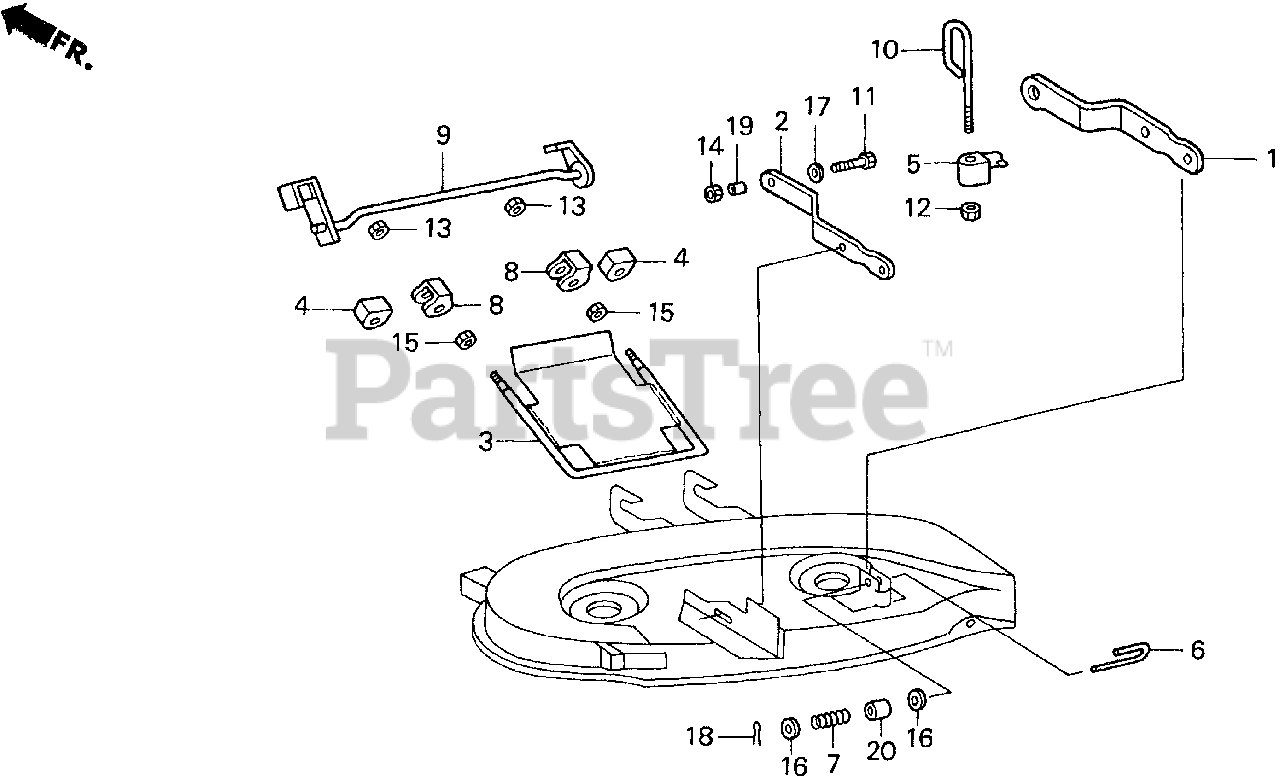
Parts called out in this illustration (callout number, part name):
1	LINK, R. RR. DECK
2	LINK, L. RR. DECK
3	ROD, CUTTER DECK LIFT
4	PIN, RR. LINK ADJUSTING
5	PIN, RR. LINK ADJUSTING
6	PIN, LIFT ARM
7	SPRING, LIFT ARM PIN
8	BRACKET, FR. LINK
10	BAR, ADJUSTING
11	BOLT, HEX. (12X35)
12	NUT, NYLON LOCK
13	NUT C, LOCK (8MM)
14	NUT, LOCK (12MM)
15	NUT, HEX. (12MM)
16	WASHER, RELEASE PIN
17	WASHER, RR. DECK LIFT
18	PIN, DRAFT ARM COTTER
19	BUSHING, DRAFT ARM
20	BUSHING, RR. DRAFT
